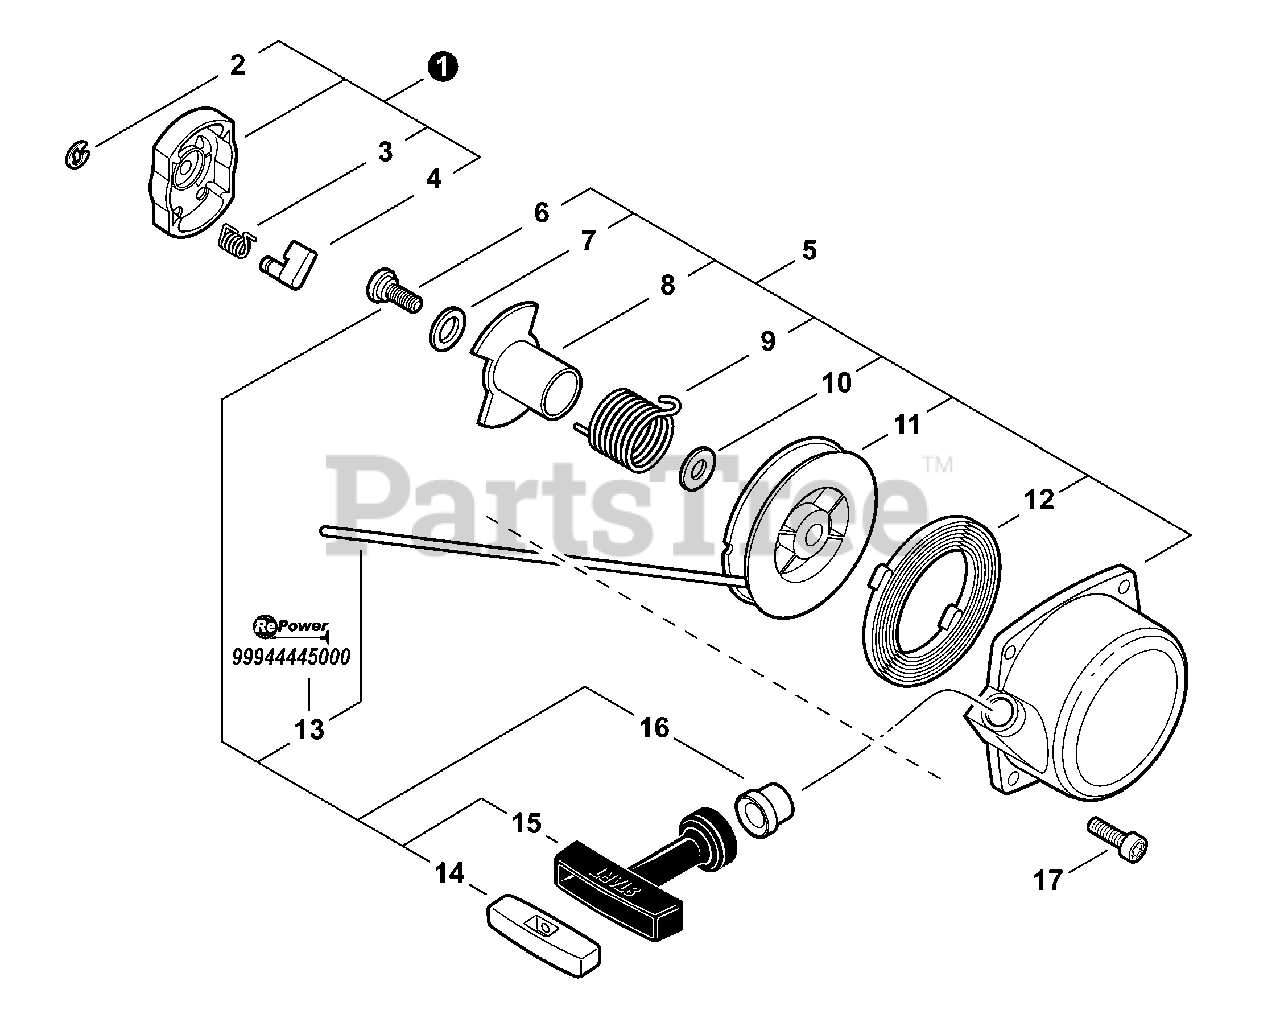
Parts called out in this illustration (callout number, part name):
1	PULLEY ASSY, STARTER
2	E-RING 4
3	SPRING, RETURN
4	PAWL, STARTER
5	STARTER ASSY, RECOIL
6	SCREW
7	WASHER, THRUST
8	PAWL CATCHER
11	REEL, ROPE
12	SPRING, RECOIL
13	ROPE, STARTER 3.5×1000 MM
14	RETAINER, ROPE
15	GRIP, STARTER
16	GUIDE, ROPE
17	SCREW 5×16
